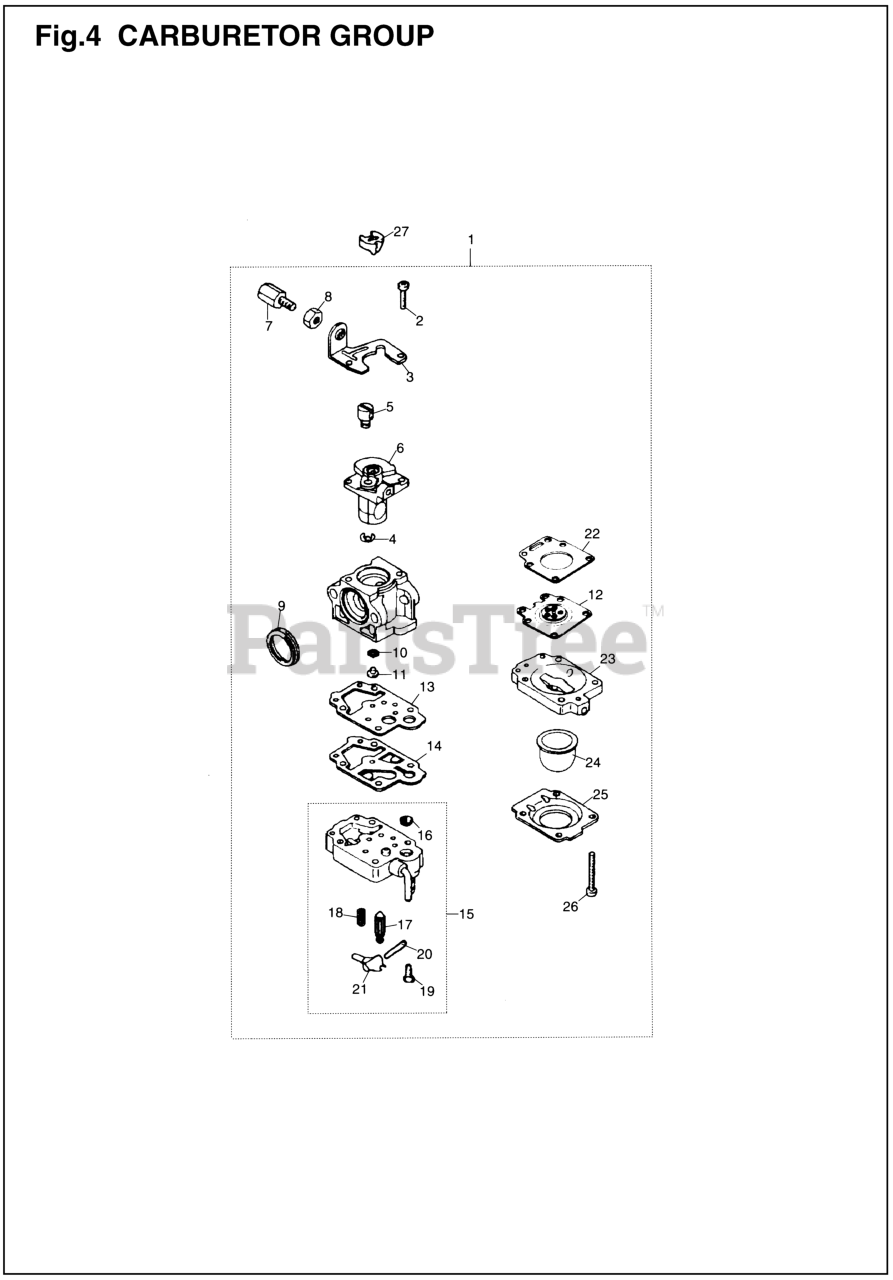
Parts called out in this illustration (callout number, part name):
1	CARBURETOR WYJ-113-1
2	SCREW
3	BRACKET
4	RING
5	SWIVEL
8	NUT
9	RING PACKING
12	DIAPHRAGM
13	GASKET
14	DIAPHRAGM
15	CARBURETOR BODY
16	SCREEN
17	VALVE INLET
25	1OVER
27	WASHER
